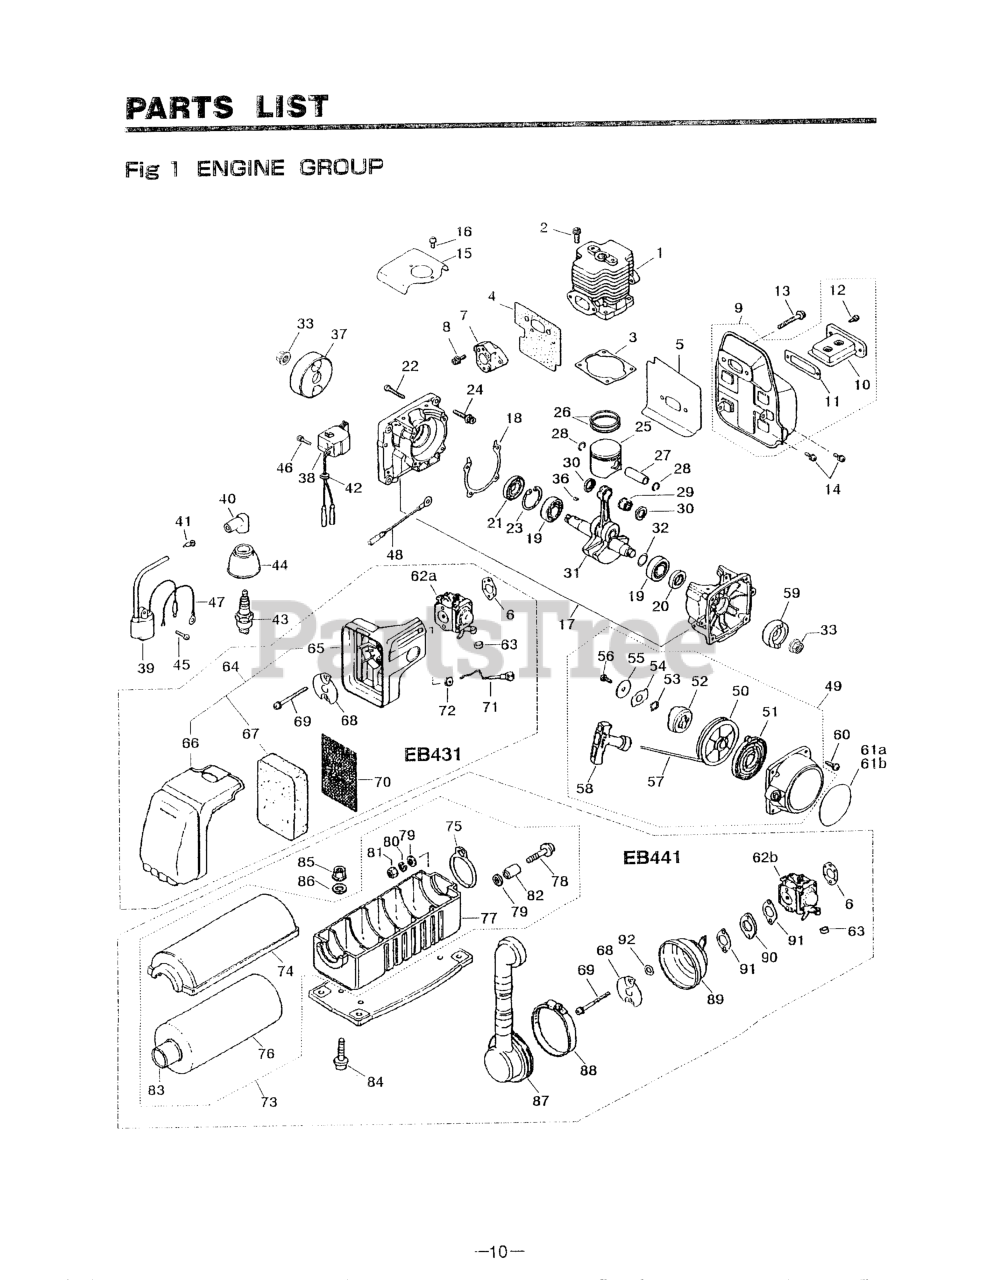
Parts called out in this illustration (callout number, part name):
1	CYLINDER (RPLS -12111)
7	INSULATOR (RPLS-14112)
9	MUFFLER (RPLS -15101)
10	ARRESTER
12	SCREW, M4 x 10
17	CRANKCASE
20	SEAL, OIL - STARTER SIDE
22	BOLT, M5 X 30
23	RING, SNAP, M35 X 1.5
26	RING, PISTON (RPLS -41210)
27	PIN, PISTON (RPLS. 1490-41316)
28	RING, SNAP
29	BEARING
30	WASHER (RPLS 1491-41510)
31	SHAFT (RPLS -42001)
32	SHIM (REPLACES 848-870-G000)
33	NUT, M10
36	KEY
39	COIL, IGNITION
41	SPRING
42	GROMMET
44	CAP (NO LONGER AVAILABLE)
45	SCREW, M4 x 16
46	BOLT, M4 X 16
47	CABLE COMPLETE
51	SPRING (RPLS -75220)
52	DOG
53	WASHER
54	RETAINER (RPLS 1861-75161)
55	WASHER
56	SCREW
57	ROPE
58	KNOB
59	PULLEY (RPLS -75210)
60	BOLT, M5 x 20
63	CAP, CABLE END
68	PLATE (REPLACES -82511)
69	SCREW, M5 X 55
73	CLEANER, AIR
74	COVER, CLEANER
75	BAND
76	ELEMENT
77	CASE, CLEANER
79	WASHER, M5 X .8
80	WASHER, SPRING M4 x 1.3
81	NUT, M5 X 4
82	COLLAR (NLA)
84	SCREW, M5 x 16
85	NUT (B)
86	WASHER, M5 X .8
87	HOSE (RPLS -83300)
88	CLAMP
89	CASE, CLEANER
NI	KIT, GASKET
